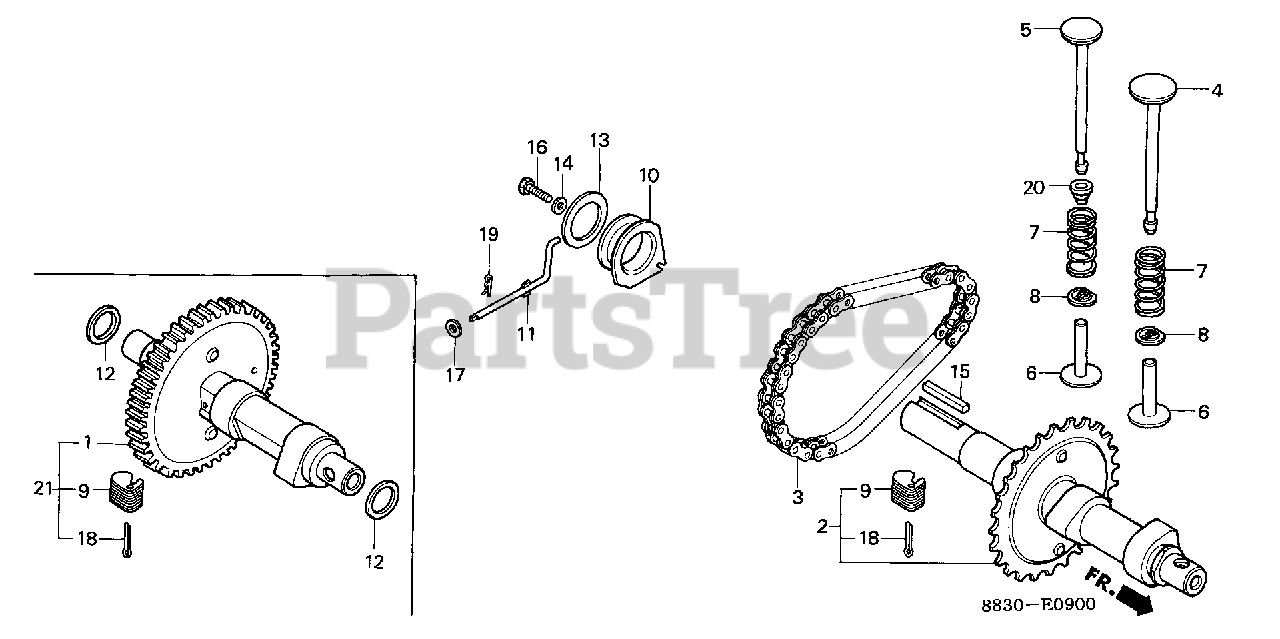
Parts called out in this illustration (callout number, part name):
4	VALVE, IN.
5	VALVE, EX.
6	LIFTER, VALVE (39.6MM) Use up to Engine SN 1119160.
6	LIFTER, VALVE (39.6MM) Use from Engine SN 1119161.
6	LIFTER, VALVE (39.9MM)
7	SPRING, VALVE
8	RETAINER, VALVE SPRING
9	WEIGHT, GOVERNOR
10	SLIDER, GOVERNOR
11	SHAFT, GOVERNOR ARM
12	WASHER, THRUST (18MM) (HELICAL GEAR)
17	WASHER, PLAIN (5MM)
17	PIN, LOCK (8MM)
18	PIN, SPLIT (3.0X25)
18	PIN, SPLIT (3.0X45)
21	CAMSHAFT ASSY.
